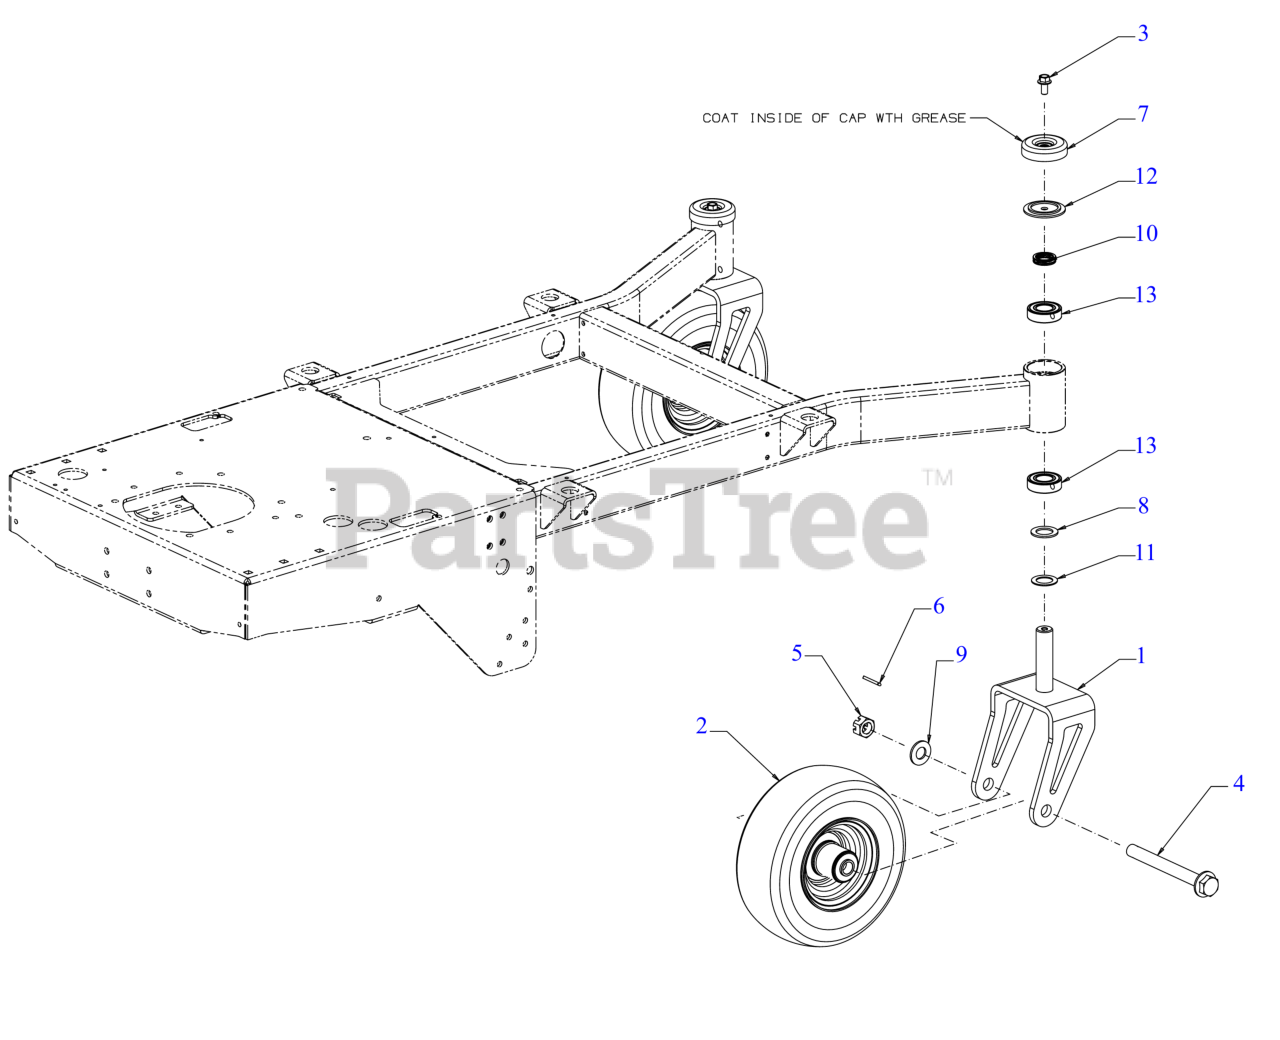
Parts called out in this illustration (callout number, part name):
1	FRONT CASTOR ASSEMBLY
2	COMPLETE WHEEL (11X4-5)
3	BOLT - 3/8-16:.75:GR5:PATCH LOCK
4	HEX FLANGE BOLT 3/4-16x7.0 GR5
5	HEX NUT CASTLE 3/4-16
6	COTTER PIN-5/32 DIA
7	AXLE CAP 2.5"
8	FLAT WASHER 1.031 X1.62 X.095
9	FLAT WASHER
10	WAVE WASHER
11	WASHER 1.010X1.560X.060
12	SHOULDER SPACER
13	BALL BEARING (1.0 x 52 x 15)
